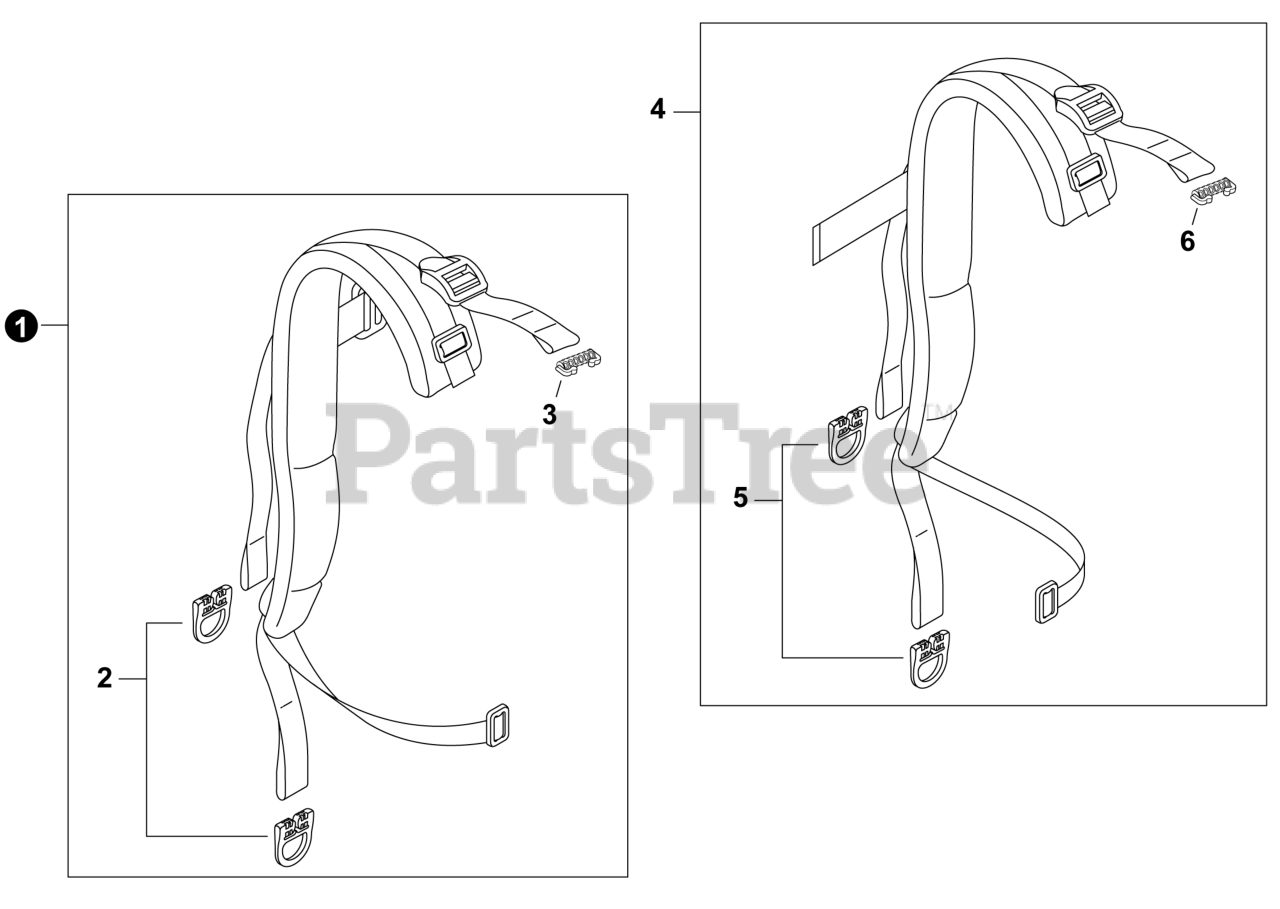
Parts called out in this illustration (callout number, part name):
1	HARNESS ASSY, LEFT
2	BUCKLE, HARNESS
4	HARNESS ASSY, RIGHT
5	BUCKLE, HARNESS
